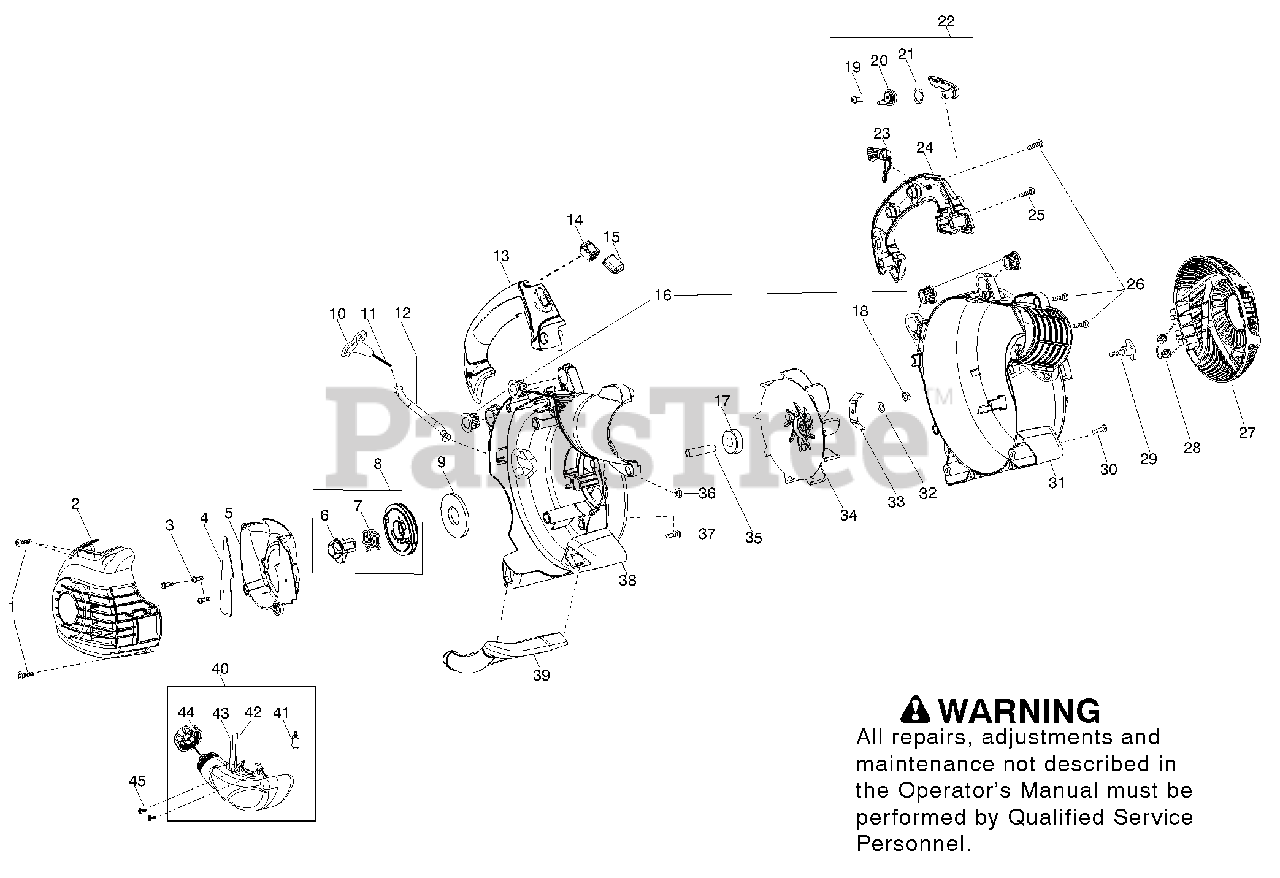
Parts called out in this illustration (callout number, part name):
2	Assy - Engine Cover
4	Shield - Baffle
7	Spring - Pulley
8	Kit - Starter Pulley
9	Spring -Starter
10	Handle - starter
12	Tube - Starter Rope
14	Kit - Switch
15	Protector - Switch
20	Rachet - Cruise Control
21	Washer - Wave
22	Kit - Cruise Control
23	Trigger - Throttle
24	Handle - LH
28	Spring - Vac Door
29	Knob - Blower
30	Screw - Vac Handle
31	Assy - Scroll LH
32	Washer - Lock
33	Blade - Mulch
34	Assy - Impeller
35	Spacer - Flywheel
36	Nut - Blower Knob
38	Assy - Scroll RH
40	Assy - Fuel Tank
41	Assy - Fuel Pickup
42	Kit - Fuel Line (carb/purge)
43	Kit - Fuel Line (tank/purge)
44	Assy - Fuel Cap w/retainer
45	Screw - Fuel Tank Retainer
